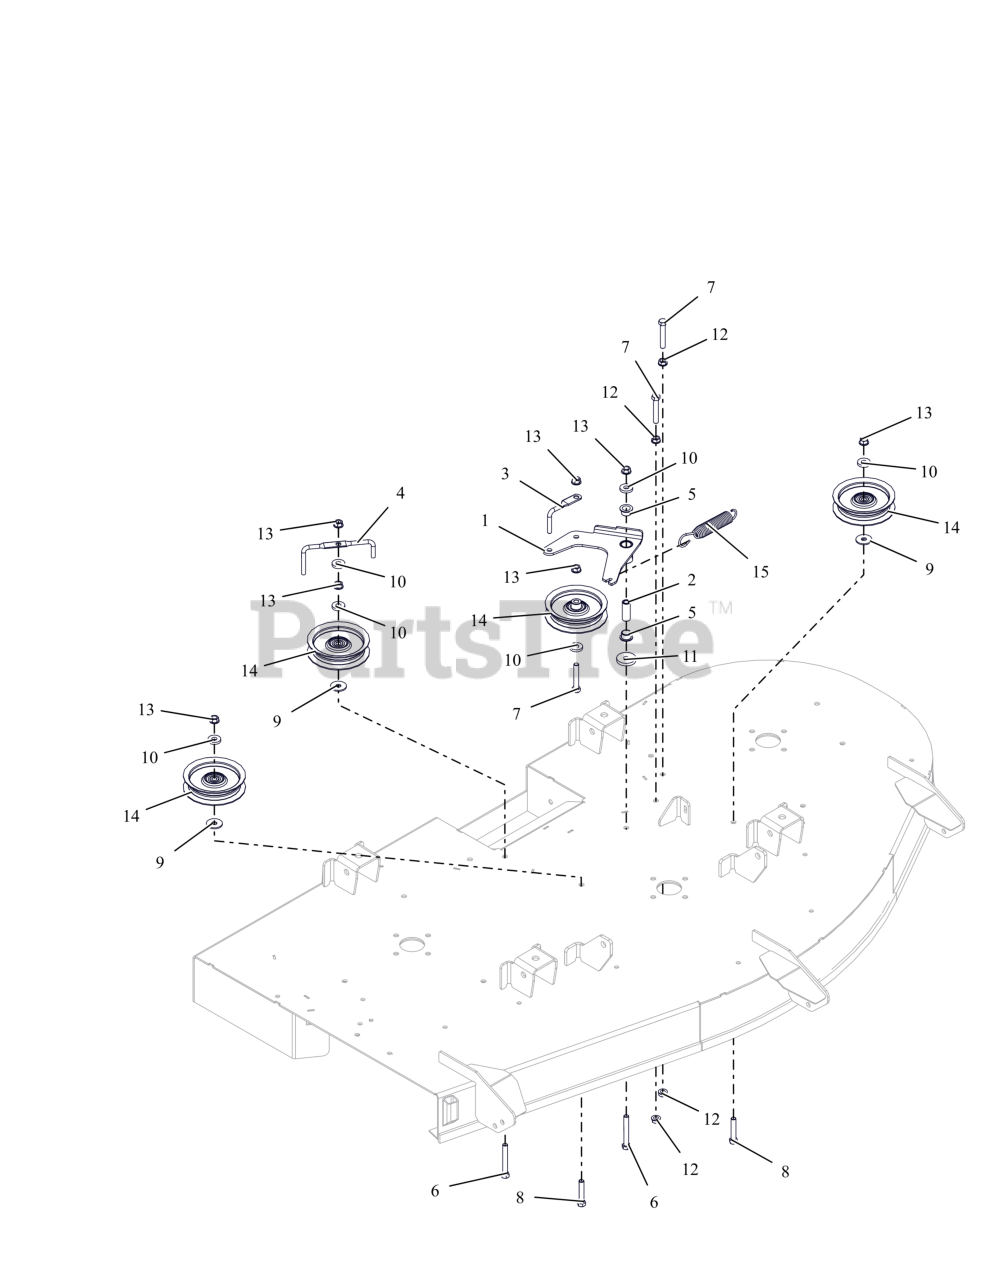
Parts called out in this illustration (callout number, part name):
1	WLDMT, IDLER ARM-42"
2	SPACER, .375IDX.625ODX1.66 PM
3	WIREFORM-BELT FINGER
4	BELT FINGER
5	BSHG-FLG, .625X.750X.500X1.00
6	BLT, HEX .38-16X2.75 G5 ZCC
7	BLT,HEX .38-16X2.25 G5 ZCC
8	BLT,HEX .38-16X2.00 G5 ZCC
9	WSHR FL STL .406X1.25X.10ZC120
10	WSHR, FLT .406X1.00X.188 ZCC
11	WSHR, FLT .406X1.50X.245 ZCC
12	NUT, SPNLK-FLG .38-16 G5 ZCC
13	NUT-LK-CTR-FLG .375-16 GF ZCC
14	IDLER, FLAT - 4.06" X .75"
15	SG-TENS .135X.98X6.0 WLD 62
